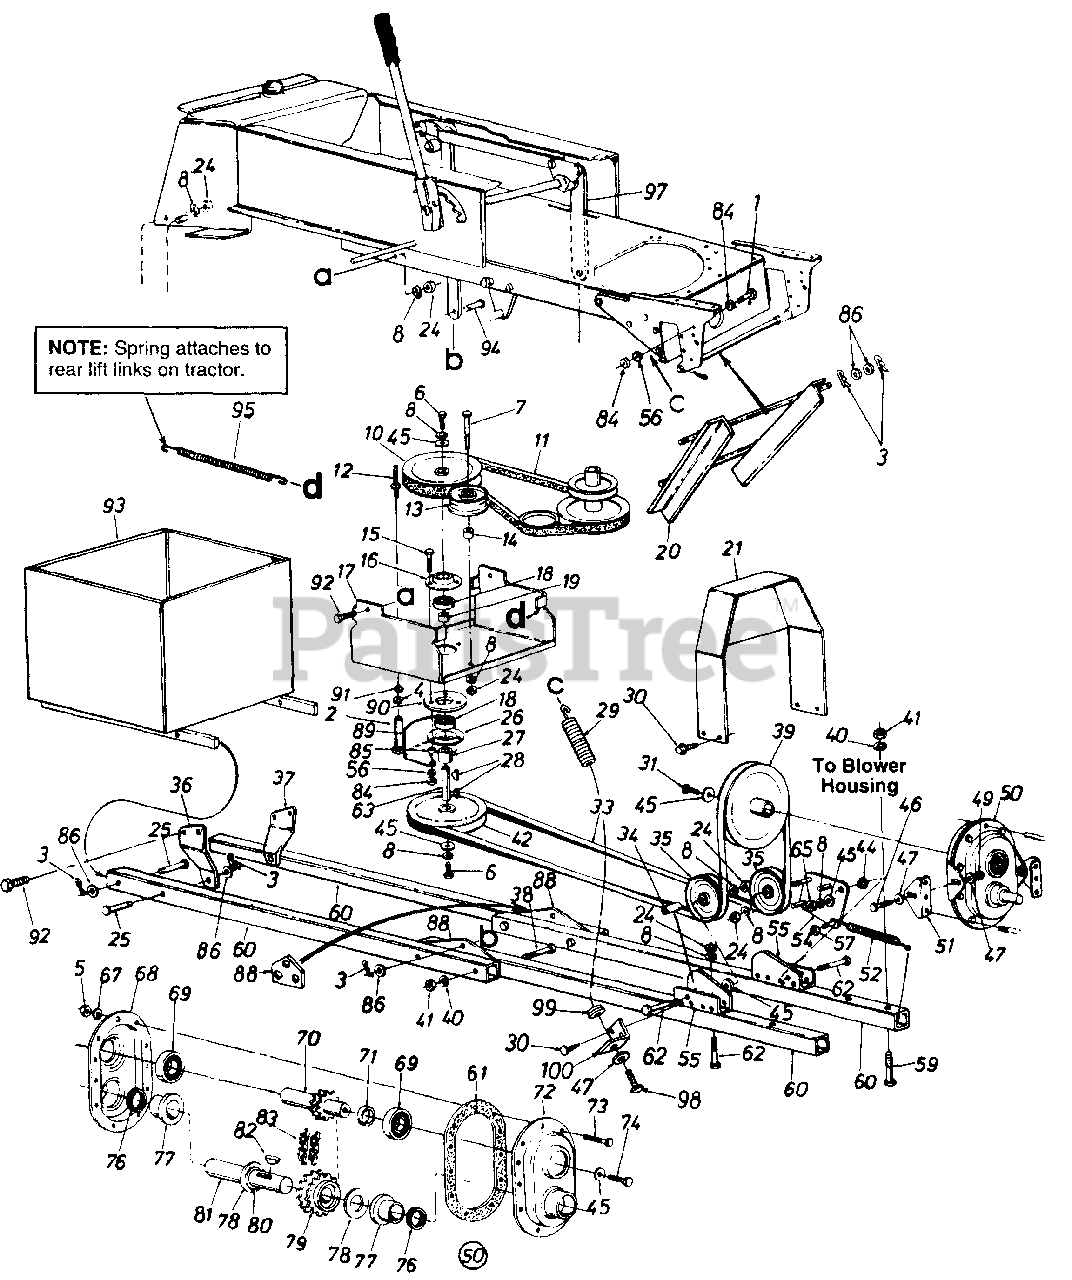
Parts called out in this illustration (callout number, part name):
1	Hex Bolt 5/16-24 x 2" Lg.
2	Clevis Pin Spec. 3/8" Dia. x 2.62" Lg.
3	Intern. Cot. Pin
4	L-Wash. 1/4" I.D.
5	Hex Nut 1/4-28 Thd.
6	Hex L-Scr. 3/8-24 x 1.0" Lg.
7	Hex Bolt 3/8-16 x 2.25" Lg.
8	L-Wash. 3/8" I.D.
10	5/8" "V"-Pulley .79" I.D. x .65" O.D.
11	"V"-Belt
12	Belt Guard Pin
13	Fl-Idler 3.75" O.D.
14	Spacer .385" I.D. x .63" O.D. x .76"
15	Hex Bolt 5/16-24 x 1.50
16	Open Brg. Hsg.
19	Spacer .8" I.D. x 1" O.D.
20	Guide Brkt. Ass'y.
21	Belt Cover Ass'y.
24	Hex Nut 3/8-16 Thd.
25	Clevis Pin .50" Dia. x 1.75" Lg.
26	Brg. Hsg. Ass'y.
27	Spacer .8" I.D. x 1" O.D. x .125"
28	Woodruff Key 3/16" x 5/8" HT
29	Helper Spring
30	Hex Wash. HD-Tap Scr. 5/16-18 x .50
31	Hex L-Scr. 3/8-24 x 1.0" Lg.
33	"V"-Belt
34	Spacer .39" I.D. x .62" O.D. x 1.74" Lg.
35	V-Idler Pulley
39	5/8" "V"-Pulley 7.5" O.D.
40	L-Wash. 1/2" I.D.
41	Hex Nut 1/2-13 Thd.
42	5/8" "V"-Pulley
44	Shld. Spacer
45	Fl-Wash. .4" I.D. x 1.25" O.D. x .16"
46	Hex Bolt 5/16-18 x 1.25" Lg.
47	Bell-Wash. .345" I.D. x .88" O.D. x .06"
49	Hex Nut 5/16-18 Thd.
50	Comp. Chain Gear Box Ass'y.
51	Gear Box Support Brkt.
52	Ext. Spring .6" Lg.
56	L-Wash. 5/16" I.D.
57	Hex Nut 3/8-24 Thd.
59	Hex Bolt 1/2-13 x 3" Lg.
60	Sq. Tubing 43" Lg.
62	Hex Bolt 3/8-16 x 3" Lg.
63	Shaft - .787" Dia. x 3.81" Lg.
65	Hex L-Nut 3/8-16 Thd.
67	Wave Spring Wash. .27" I.D. x .51" O.D. x .03"
68	Complete Gear Hsg. Half - L.H.
69	Ball Brg. 1" I.D. x 2" O.D.
70	11-2 x .5 Pitch Sprocket Shaft Ass'y.
71	Spacer 1" I.D. x 1.18" O.D. x .44"
72	Comp. Gear Hsg. Half - R.H.
73	Hex Bolt 1/4-28 x 1" Lg.
74	Hex L-Scr. 3/8-24 x 1" Lg.
76	Oil Seal 1.25" I.D.
77	Flange Brg. 1.25" I.D.
78	Fl-Wash. 1.25" I.D. x 2" O.D. x .036"
79	DBL Sprocket 19-2 Teeth x .5" Pitch
80	Snap Ring for 1.25" Dia. Shaft
81	Gear Shaft 1.25 Dia. x 6" Lg.
82	Hi-Pro Key 1/4" x 7/8"
83	40-2 Chain 1/2" Pitch x 25 Links
84	Hex Nut 5/16-24 Thd.
85	Spacer .380" I.D. x .625" O.D. x .227
86	Fl-Wash. .53" I.D. x 1" O.D. x .06"
88	Attaching Plate
91	Hex L-Nut 1/4-20 Thd.
92	Hex Bolt 3/16 x 1" Lg.
95	Extension Spring
97	Deck Lift Link Ass'y.
98	Hex Bolt 5/16-18 x 1.5" Lg.
99	Spring Insert
